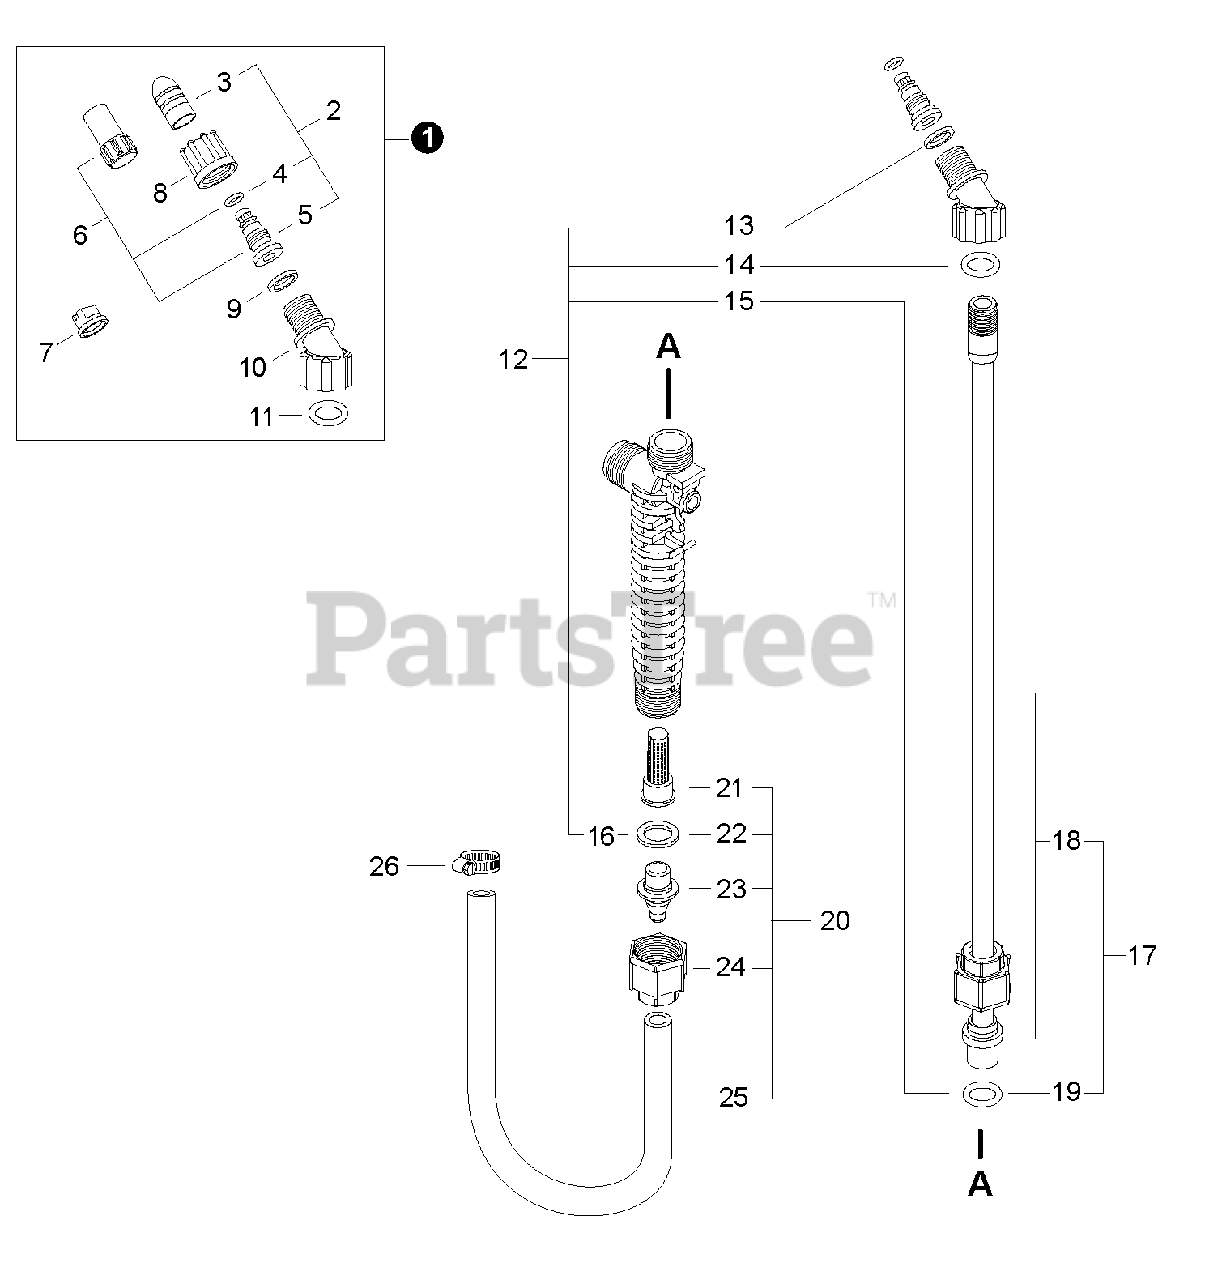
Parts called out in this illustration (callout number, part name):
1	NOZZLE KIT
2	NOZZLE KIT, BRASS
3	CAP, NOZZLE - BRASS
4	O-RING, NOZZLE
5	BODY, NOZZLE
6	NOZZLE KIT, PLASTIC
7	NOZZLE, FLAT FAN
8	NUT, NOZZLE
9	GASKET, NOZZLE
10	ELBOW, NOZZLE
11	O-RING, ELBOW
12	GASKET KIT, WAND
13	GASKET, NOZZLE
14	O-RING, ELBOW
16	GASKET, ADAPTER
17	WAND ASSY, PLASTIC
18	WAND, SPRAYER
20	HOSE KIT
21	FILTER, SPRAY GUN
22	GASKET, ADAPTER
23	ADAPTER, HOSE - BLACK
24	NUT, HOSE
26	CLAMP, HOSE
